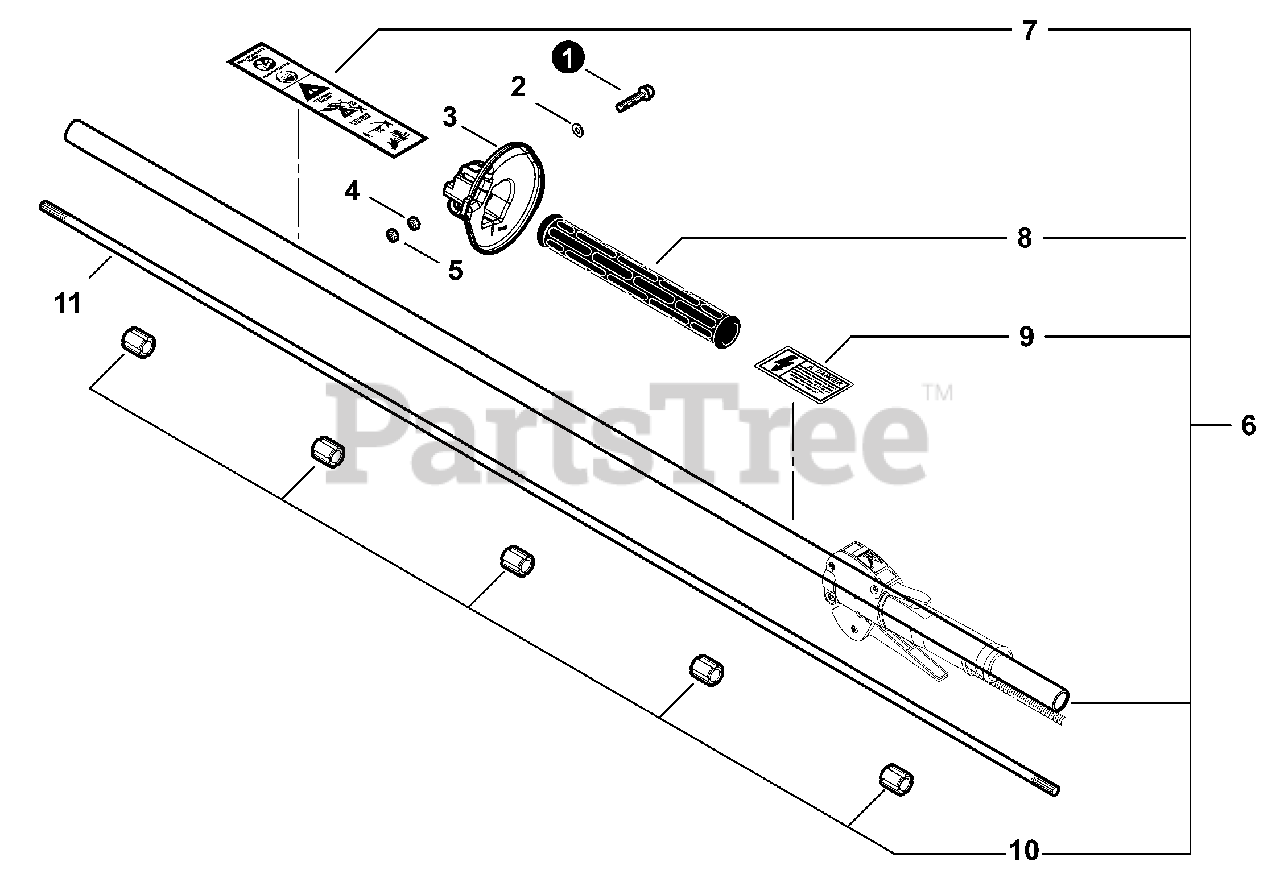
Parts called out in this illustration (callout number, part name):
1	SCREW - 5×35
2	WASHER 5.5×12×0.8
3	GUARD, HAND
4	WASHER 5.5×12×0.8
5	NUT, LOCK M5
6	MAIN PIPE ASSY WITH GRIP
7	LABEL, CAUTION
8	GRIP, FRONT
9	LABEL, HIGH VOLTAGE
10	BUSHING
11	MAINSHAFT
